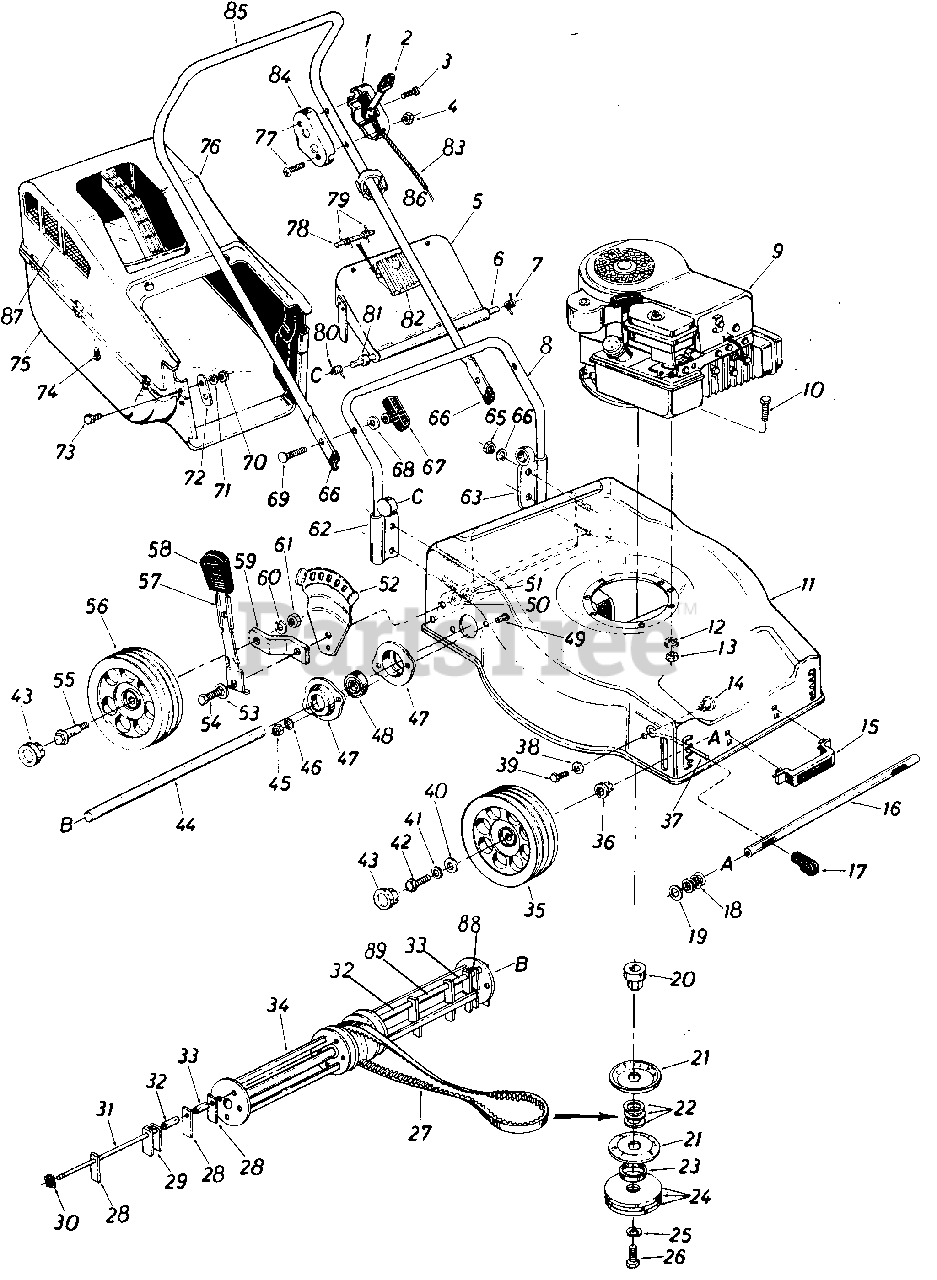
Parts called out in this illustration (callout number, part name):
1	Throttle Control Housing
2	Throttle Control Lever
3	Sheet Metal Screw M5 x 30
4	Hex Nut M5
5	Deflector-Chute
6	Pivot Shaft-Chute Deflector
7	Torsion Spring-L.H.
8	Lower Handle
9	Engine
10	Hex Bolt M8 x 30
12	Lock Washer B8
13	Hex Nut M8
14	Spacer
15	Deck Handle-Front
16	Front Axle
17	Knob-for Front Height Adj.
18	Compression Spring
19	Spring Spacer
20	Pulley Hub
21	Pulley "V" Belt
22	Spacers
23	Spacer
24	Fly Wheel
25	Lock Washer
26	Hex Bolt 3/8" x 45 UNF
27	"V"-Belt
28	Thatcher Blade
29	Lift Blade
30	Snap Ring 8M
31	Thatcher Blade Shaft
32	Spacer
33	Spacer
34	Thatcher Rotor
35	Front Wheel
36	Spring Spacer
37	Front Height Adjustment Lever
38	Lock Washer B6
39	Hex Bolt M6 x 12
40	Flat Wash 0 15
41	Belleville Washer M12
42	Hex Bolt M12 x 16
43	Hub Cap
44	Thatcher Blade Shaft
45	Hex Nut M6
46	Lock Washer M6
47	Flange Bearing w/Housing
49	Mach. Screw M6 x 16
50	Lock V\lasher B 10
51	Hex Nut M10
52	Index Plate
53	Belleville Washer
54	Hex Bolt M10 x 20
55	Rear Wheel Axle Bolt
56	Rear Wheel
57	Spring Lever w/Knob
59	Pivot Bracket
60	Lock Washer B10
61	Hex Nut M10
62	Handle Bracket-R.H.
63	Handle Bracket-L.H.
65	Hex Nut M8
66	Handle Cap
67	Wing Nut M6
68	Lock Washer 6.4
69	Mach. Screw M6 x 50
70	Hex Nut
71	Lock Washer
72	Reinforcement Plate
73	Mach. Screw B3.92 x 32
74	Mach. Screw Self Tap B3.9 x 9.5
75	Grass Bag-Lower Half
76	Grass Bag-Upper Half
77	Screw B2.9 x 9.5
78	Pivot Pin
79	Torsion Spring for Door Snap
80	Torsion Spring-R.H.
81	Spring Spacer
82	Door Snap
83	Throttle Control Wire
84	Throttle Control Housing
85	Upper Housing
86	Cable Tie
87	Screen
88	Spacer" Lg.
89	Spacer 1 3/4" Lg.
